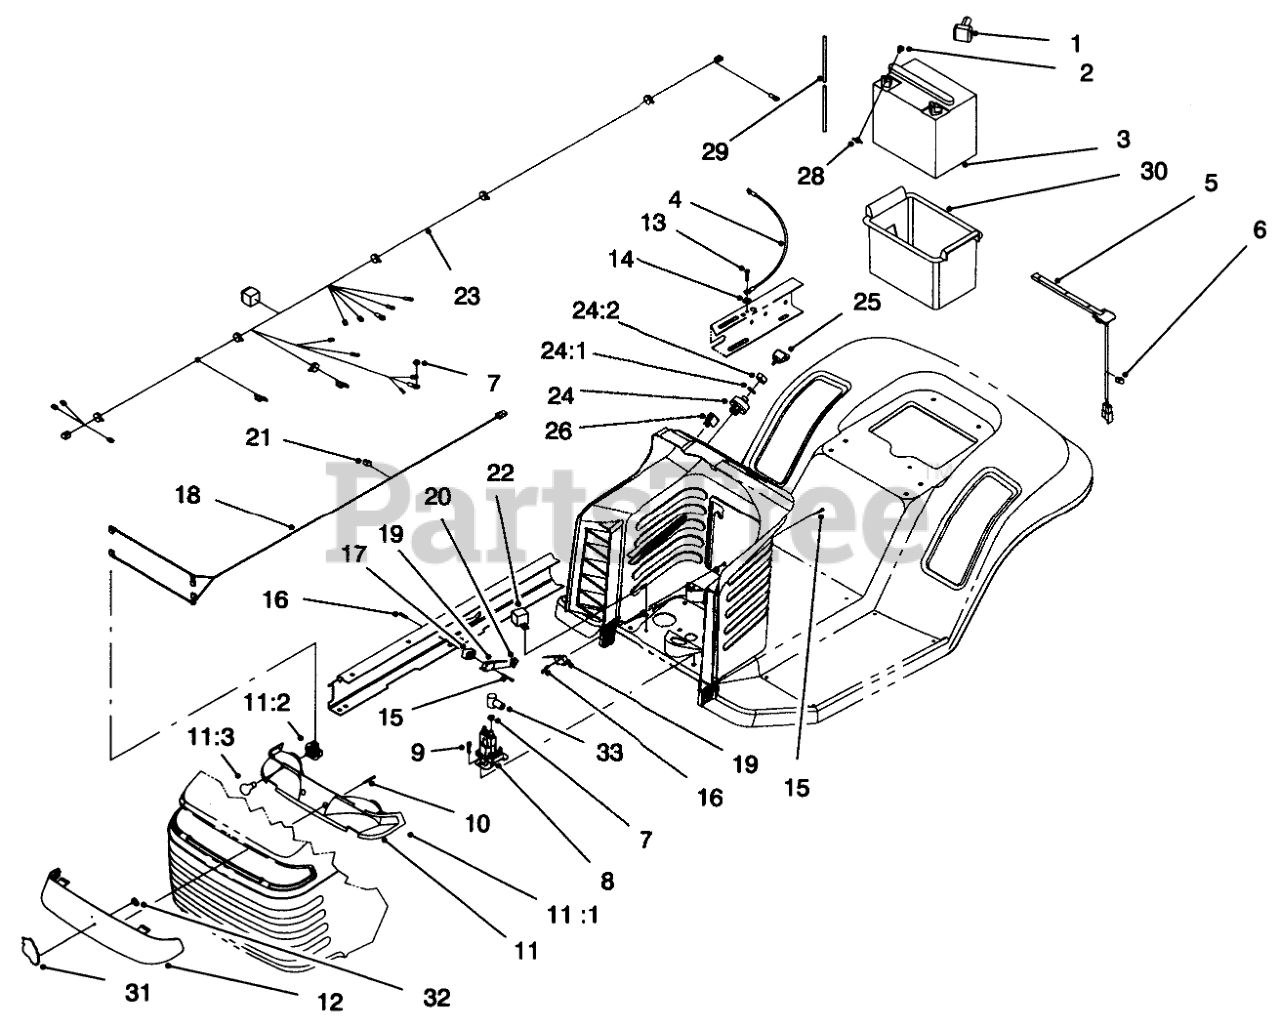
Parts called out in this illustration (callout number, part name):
1	BOOT-TERMINAL
2	SCREW-HH
3	Battery
4	WIRE ASM
5	SWITCH-SEAT
6	CLIP-RETAINER, WIRE
7	NUT-KEPS
8	Solenoid
9	SCREW-HWH
11	Reflector-Lamp Asm (Incl. Ref. #11:1-11:3)
11:1	REFLECTOR-LIGHT
11:2	SOCKET-LIGHT
11:3	BULB
12	LENS-HEADLIGHT
13	SCREW-HWH
14	WASHER-LOCK/EXT
15	SCREW-HH
16	NUT-SPEED
17	SPACER
18	HARNESS-WIRE, LIGHTS
19	SWITCH-MICRO
20	PLUNGER-SEAL
21	CLIP-RETAINER, WIRE
22	RELAY
23	WIRE HARNESS
24	Key Switch ASM
24:1	WASHER-TOOTH, INTERNAL
24:2	NUT-HH
25	KEY-IGNITION
26	SWITCH-ROCKER
28	NUT-WING
29	TUBE-BATT DRAIN/80-2600
30	BOX-BATTERY
31	EMBLEM-GRILLE WHEELHORSE
33	BOOT-TERMINAL INSULATOR
